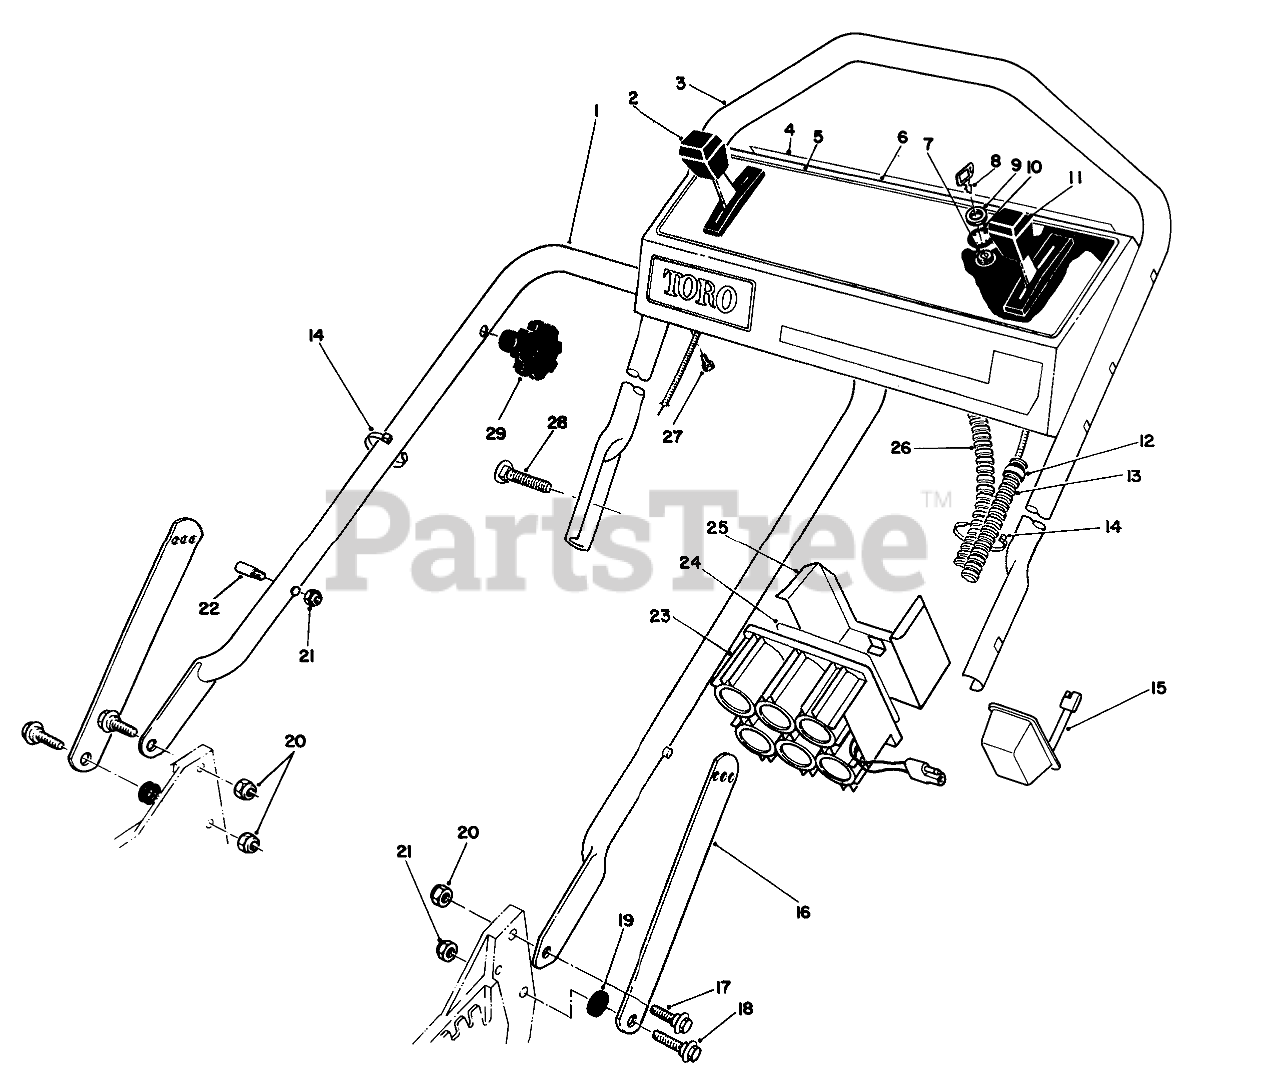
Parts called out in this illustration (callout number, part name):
1	LOWER HANDLE ASM
2	Control-Ground Speed
3	UPPER HANDLE
4	DECAL-PANEL, DANGER
5	DECAL - INSTRUCTIONS
6	Panel-Control (Incl. Ref. #4 & 5)
7	STARTER SWITCH ASM
8	KEY-IGNITION
9	NUT-HH
10	WASHER-TOOTH, INTERNAL
11	THROTTLE CONTROL
12	FITTING-RING
13	CONTROL CABLE COVER
14	TIE-CABLE
15	Charger
16	Handle Latch
17	SCREW-SHOULDER
18	SCREW-SHOULDER
19	SPACER
20	NUT-LOCK, NI
21	NUT-LOCK, NI
22	HANDLE PIN
23	BATTERY ASSEMBLY
24	Decal
25	Retainer-Battery
26	Harness-Wire
27	SCREW-HWHTF
28	5/16-18 X 2 HNDLE SCREW
